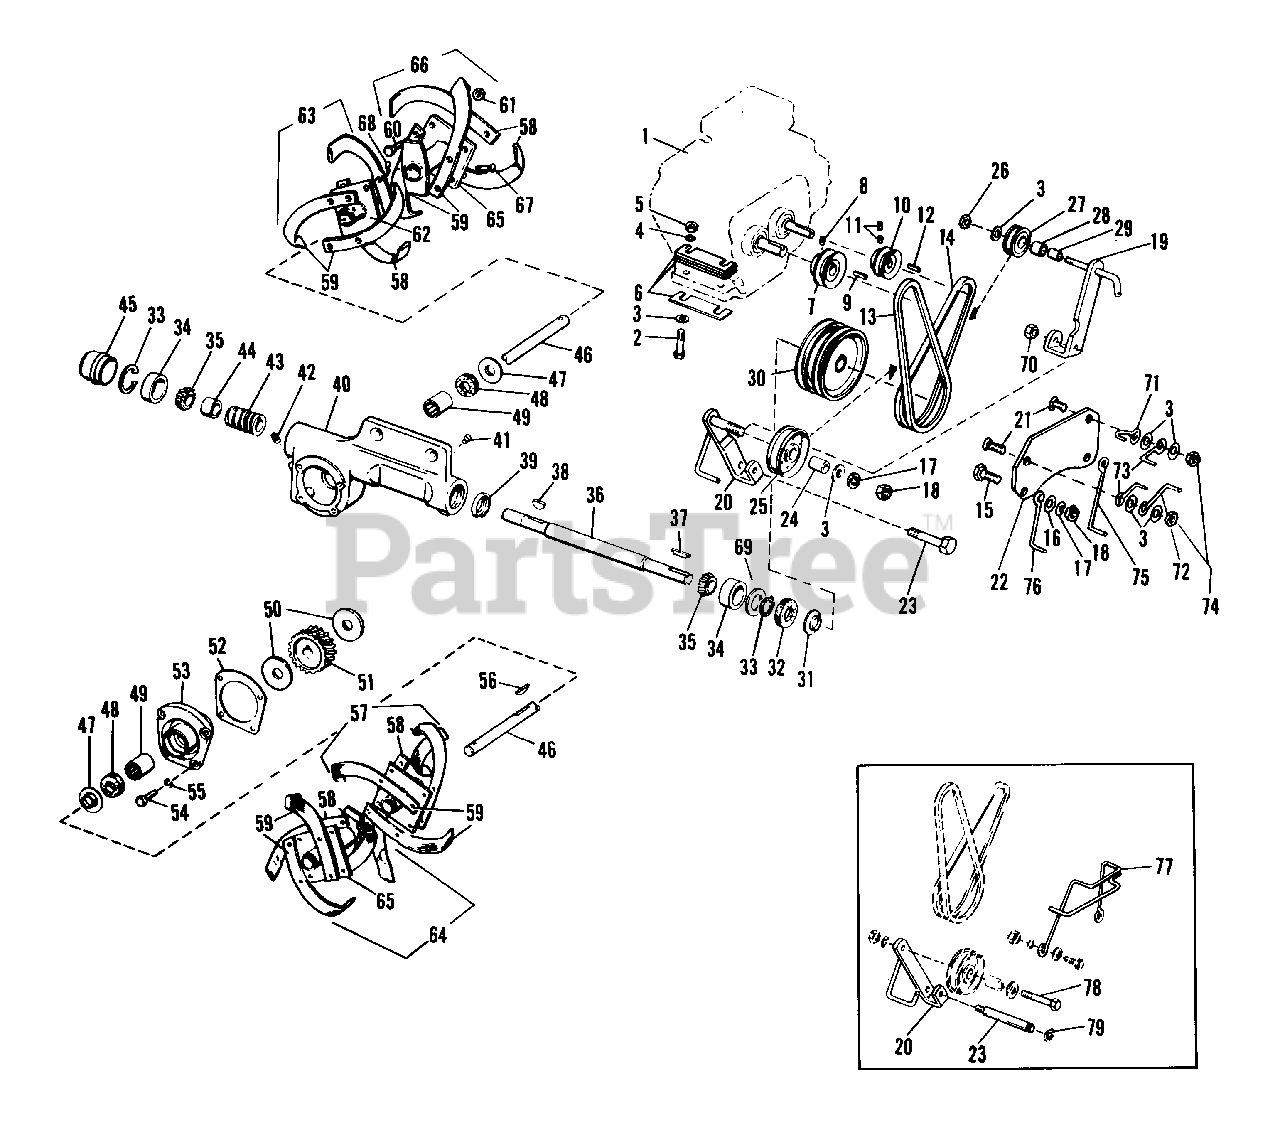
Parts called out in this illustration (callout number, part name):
2	CAPSCREW, Hex Hd., 5/16-18 x 2
3	WASHER, Plain, 5/16
4	LOCKWASHER, 5/16
5	NUT, Hex, Full, 5/16-18
7	PULLEY, Engine
8	SETSCREW, 5/16-18 x 3/8
9	KEY, Square
10	PULLEY, Engine
11	SETSCREW, 5/16-18 x 5/16
13	BELT, V, Reverse
14	BELT, V, Forward
15	CAPSCREW, Hex Hd., 3/8-18 x 1
16	WASHER, Plain, 3/8
17	LOCKWASHER, 3/8
18	NUT, Hex, Full, 3/8-16
19	LEVER ASSY, Idler
19	LEVER ASSY, Idler (1600400 Only)
20	LEVER ASSY, Idler
21	BOLT, Carriage, 3/8-16 x 1
22	PLATE
23	BOLT, Pivot
23	PIN, Pivot
24	SPACER
25	PULLEY, Idler
26	LOCKNUT, 3/8-16
27	PULLEY, Idler Assy
30	PULLEY, Driven
33	RING, Snap
34	CUP, Bearing
35	BEARING, Roller
36	SHAFT, Worm
40	HOUSING, Worm Drive
42	PLUG, Pipe, 3/8
43	WORM, R.H.
45	CAP, Hub
46	SHAFT, Worm Gear
49	BEARING, Needle
50	WASHER, Thrust
51	GEAR, Worm, R.H.
54	CAPSCREW, Hex Hd., 1/4-20 x 5/8
55	LOCKWASHER, 1/4
56	KEY, Woodruff
57	TINE ASSY, L.H. Inner
58	TINE BLADE, L.H
59	TINE BLADE, R.H.
60	CAPSCREW, Hex, 7/16-20 x 1-1/4
61	NUT, Hex, Full, 7/16-20
62	TINE PLATE ASSY, Inner
63	TINE BLADE ASSY, R.H. Inner
64	BLADE ASSY, L.H. Tine
65	BLADE ASSY, Tine Ext.
66	BLADE ASSY, R.H. Tine
67	PIN
68	PIN, Cotter, 1/8 x 3/4
69	BACKING RING or 171762 BACKING RING
70	NUT, Whiz Lock
71	STOP, Belt
72	STOP, Belt
73	STOP, Belt
74	LOCKNUT, 3/8-16
75	STOP, Belt
76	STOP, Belt
77	STOP, Belt
78	CAPSCREW, Hex Hd. 3/8-16 x 1-1/2
79	RING, Retaining
